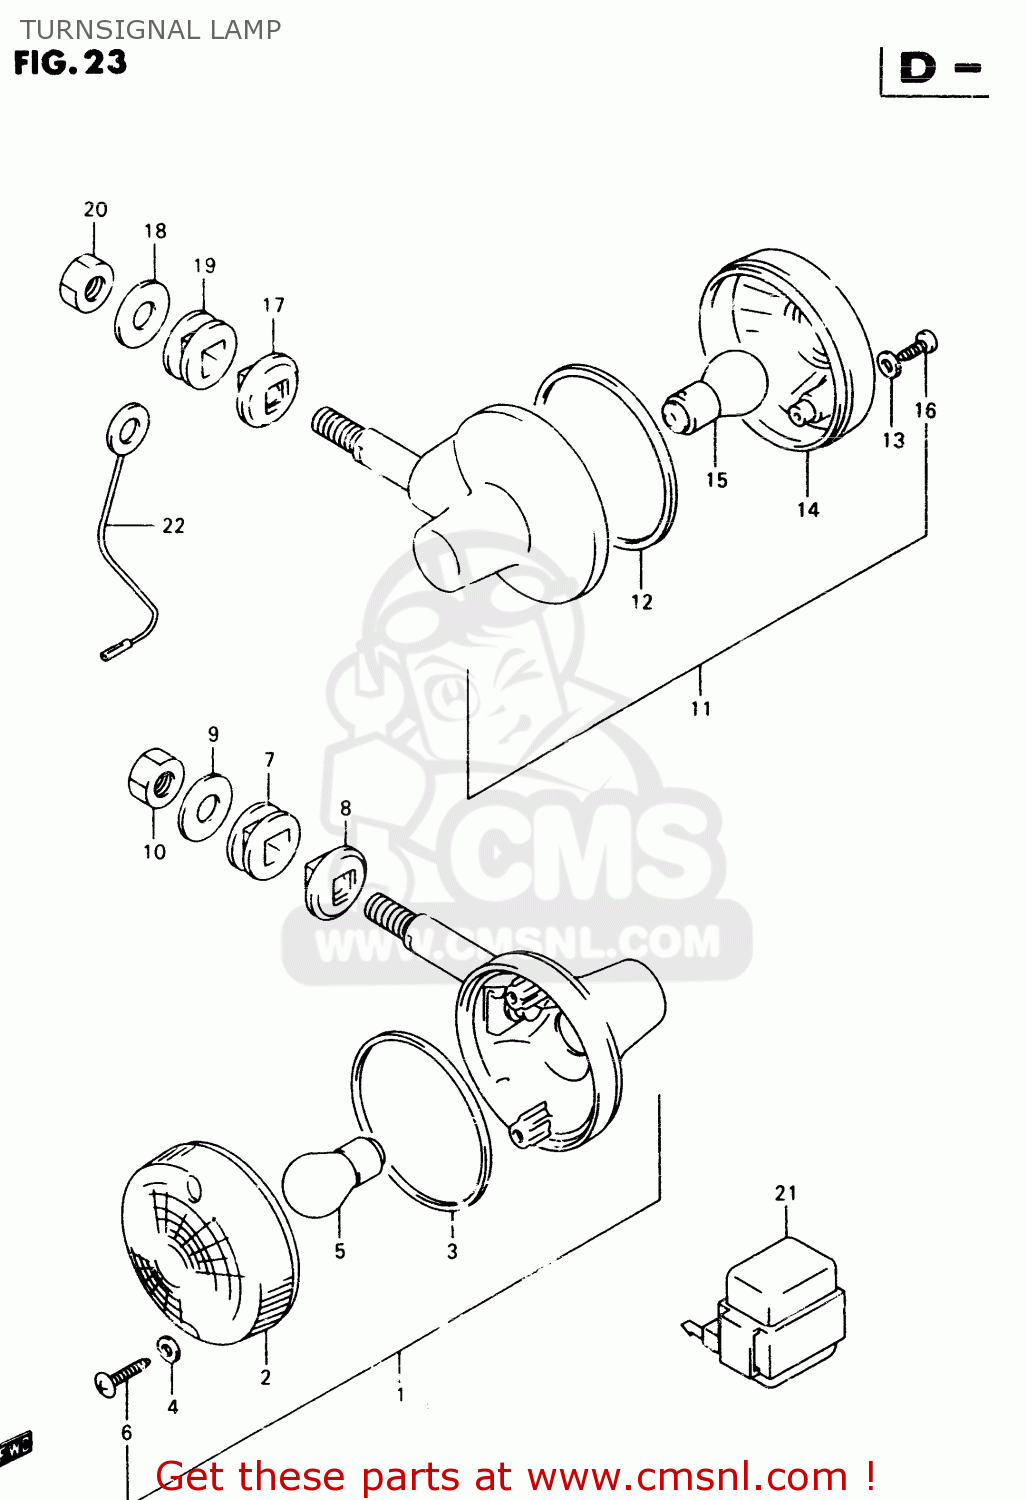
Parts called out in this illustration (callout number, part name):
1	LAMP ASSY,FR TURN SIGNAL
2	LENS
3	GASKET (NAS)
4	GASKET (NAS)
5	BULB(12V21W)
6	SCREW
7	CUSHION
8	SPACER
9	WASHER (10.5X30X2.3)
10	NUT
11	LAMP ASSY,RR TURNSIGNAL
12	LENS
13	GASKET (NAS)
14	LENS
15	BULB(12V21W)
16	SCREW
17	SPACER
18	WASHER (10.5X30X2.3)
19	CUSHION
20	NUT
21	RELAY ASSY
22	LEAD WIRE,EARTH
